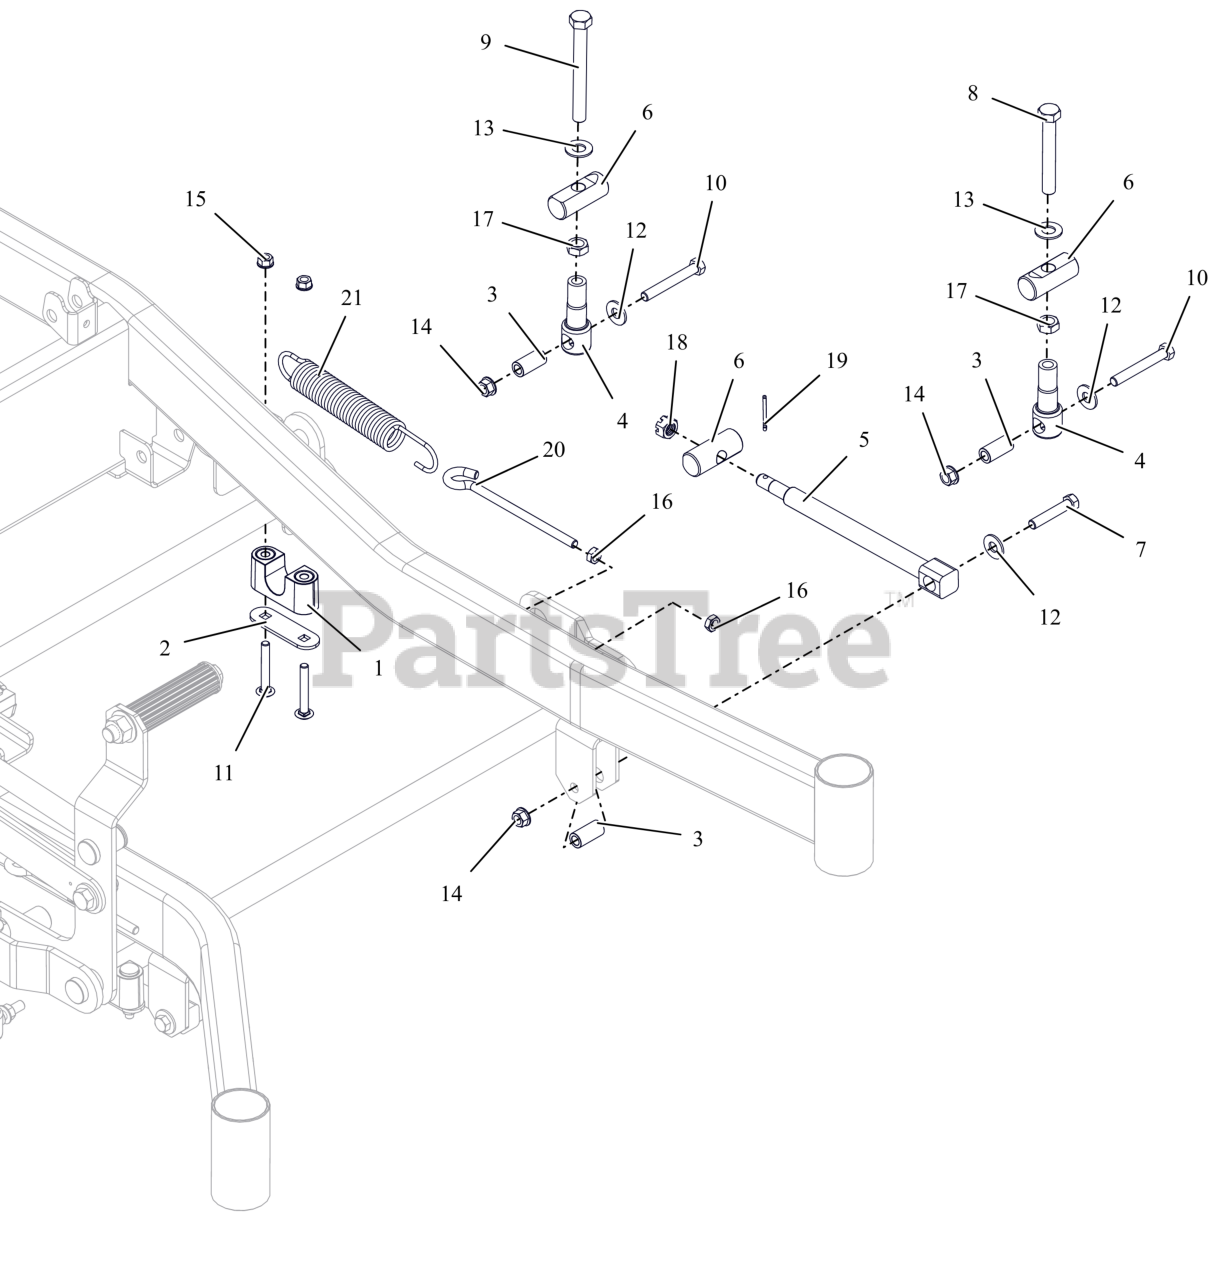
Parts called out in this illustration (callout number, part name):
1	ASM-BUSHING, DECK LIFT
2	PLATE, BEARING SUPPORT
3	SPACER, DECK LEVELING
4	LINK, DECK LIFT FORMED
5	DRAG,LINK-HD
6	PIN, DECK LIFT
7	BLT,HEX .38-16X2.00 G5 ZCC
8	BLT, HEX .50-13X3.50F G5 ZCC
9	BLT, HEX .50-13X4.50F G8 ZCC
10	BLT, HEX .38-16X2.75 G8 ZCC
11	BLT, RHSSN.31-18X2.25 G5 ZCC
12	WSHR,FLT .438X1.00X.083 ZCC
13	WSHR, FLT .557X1.040X.102 ZCC
14	NUT-LK-TOP-FLG .38-16 ZC120
15	NUT,LK-CTR-FLG .31-18 GF ZCC
16	NUT-JAM .375-16 G2 ZCC
17	NUT-JAM .500-13 G2 ZCC
18	NUT-SL .50-13
19	PIN,CTR.12X1.25EXTPRSQCT ZC120
20	BOLT,.38-16 X 5.25-.62 DIA EYE
21	SG-TENS .162X1.25X8.25 WLD 25
